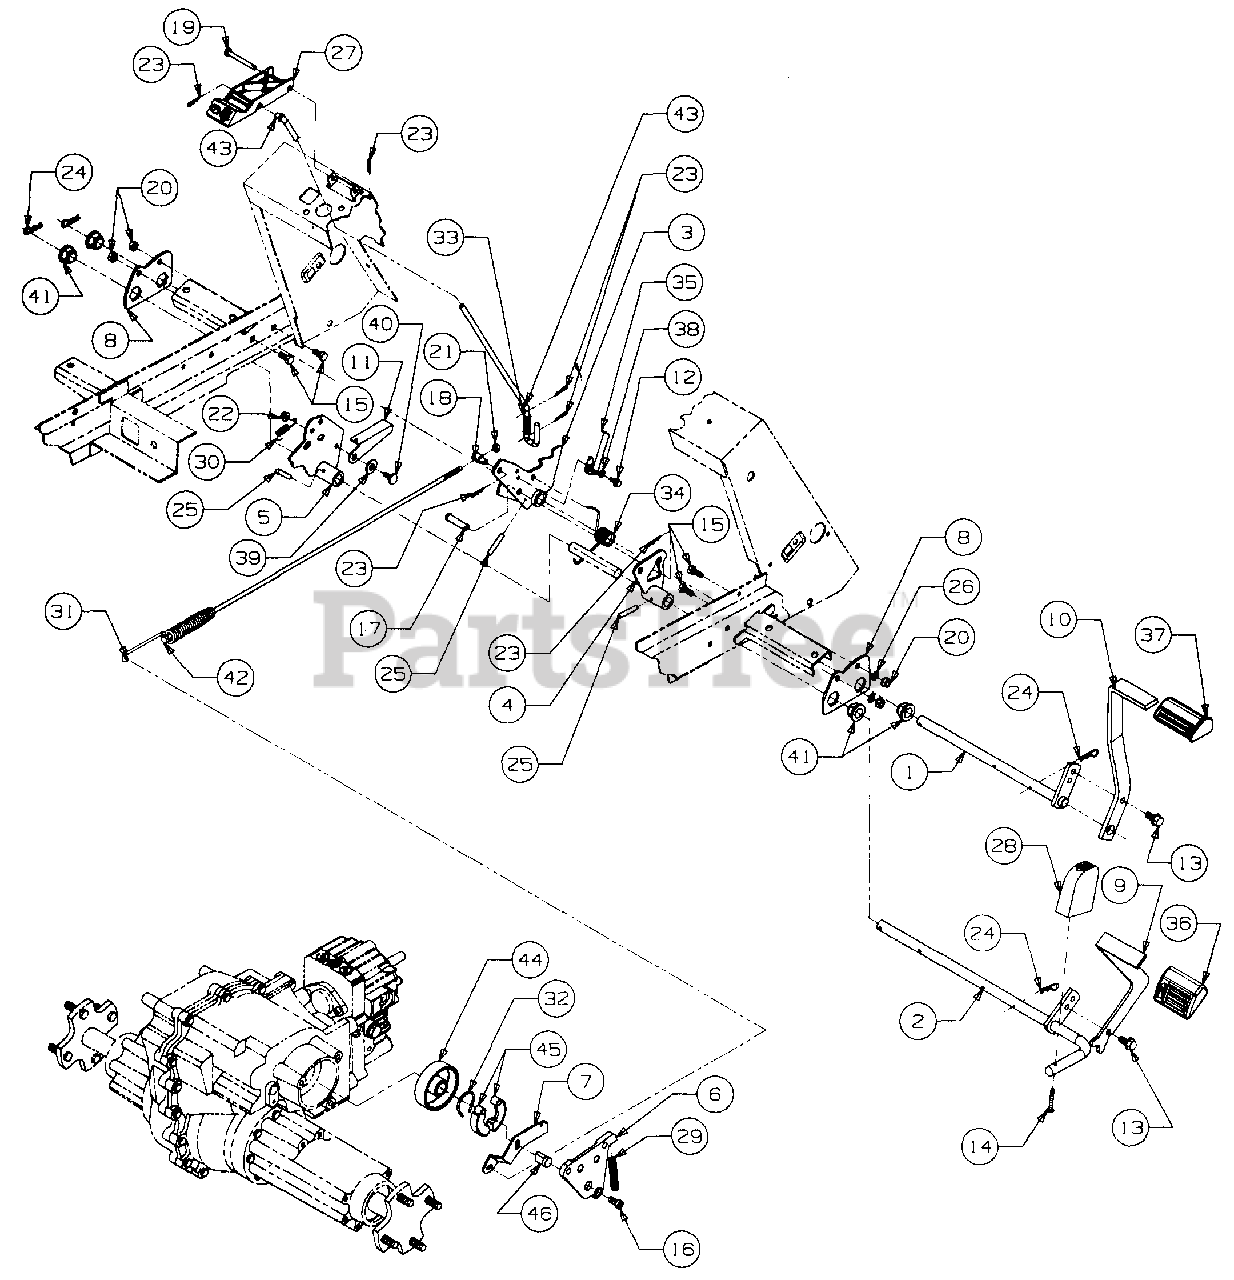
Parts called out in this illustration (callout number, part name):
1	Shaft Assy, Brake
2	Shaft Assy, Clutch
7	Arm, Brake
8	Plate, Pedal Mounting
11	Actuator, Reverse Switch
12	Screw, Hex Wash Tapp 1/4 x .50 Lg
13	Screw, Hex Wash TT-Tapp, 3/8 x .75 Lg
14	Screw, Truss Mach Tapp, #12 X 1.5 Lg.
15	Screw, Hex Cap, 5/16-18 x .75 Lg GR5
16	Screw, Low Hd Cap, 3/8-16 x .75 Lg
17	Pin, Clevis, 3/8 OD x 1.62 Lg
18	Ferrule, Adjustment
19	Pin, Clevis, 1/4 OD x 2.38 Lg
20	Nut, Hex Sems, 5/16-18
21	Nut, Hex Sems, 1/4-20
22	Nut, Hex Flange Lock, 1/4-20
23	Pin, Internal Cotter, 5/16 Dia x 1.12 Lg
24	Pin, Internal Cotter, 3/8 Dia x 1.625 Lg
25	Pin, Spiral Spring, 1/4 Dia x 1.5 Lg
26	Nut, Push Speed, 5/16 ID
27	Lever, Park Brake
28	Pad, Reverse Pedal
29	Spring, Compression
30	Spring, Extension, .38 OD x 2.10 Lg
31	Spring, Extension, .75 OD x 5.0 Lg
32	Spring, Brake
33	Spring, Compression, .50 OD x 2.23 Lg
34	Spring, Torsion
35	Actuator, Neutral Switch
36	Pad, Forward Pedal
37	Pad, Brake Pedal
38	Washer, Flat, .281 x .50 x .063 Thk
39	Washer, Flat, .406 x .75 x .063 Thk
40	Bolt, Shoulder, .375 Dia X. 181 Lg
41	Bearing, Hex Flange
42	Rod, Brake
43	Rod, Park Brake Engagement
44	Drum, Brake
45	Shoe, Brake
46	Actuator, Brake Shoe
